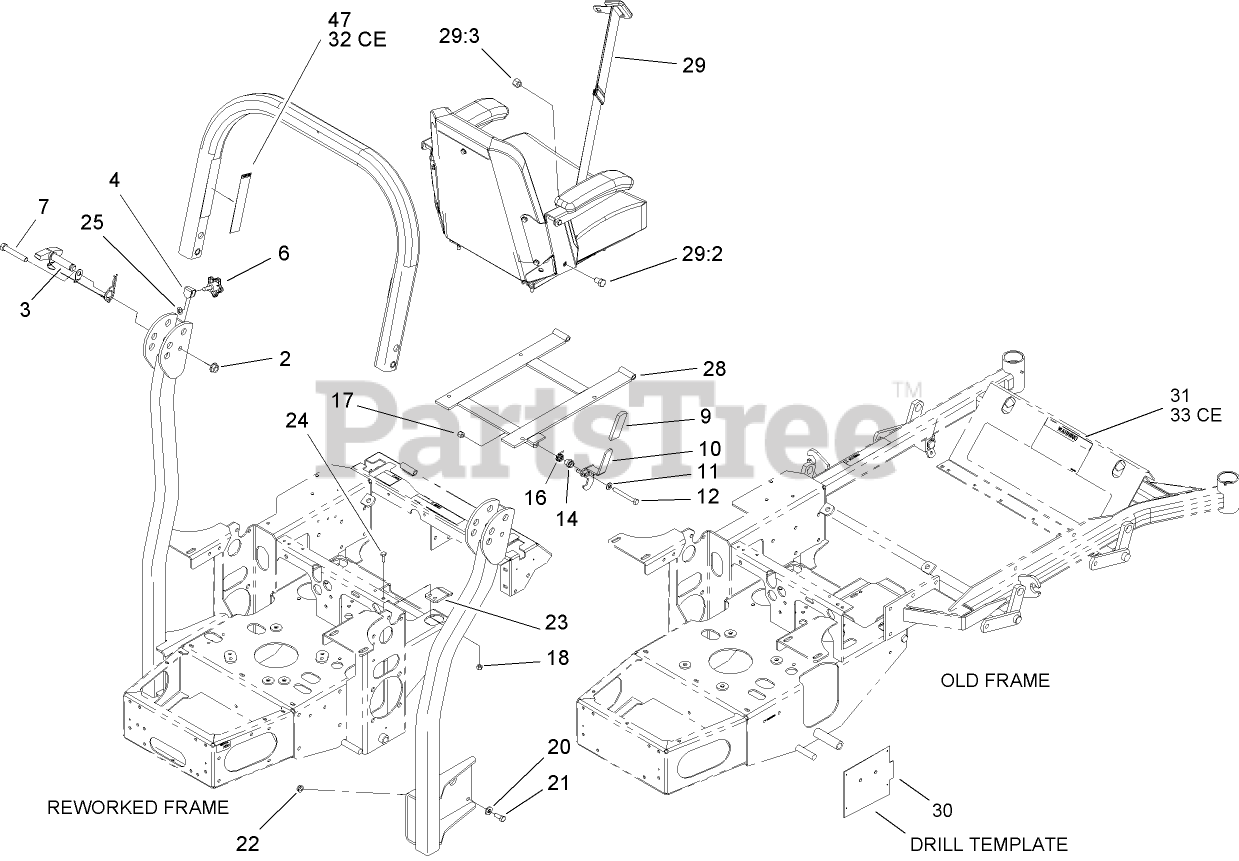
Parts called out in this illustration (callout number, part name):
2	NUT-HF
3	PIN LATCH ASM
7	SCREW-HH
9	GRIP-HANDLE
10	LATCH ASM
11	WASHER-FLAT
12	SCREW-HH
14	BUSHING-LATCH, SEAT
16	SPRING-TORSION
17	NUT-LOCK, NI
18	NUT-LOCK, NI
20	WASHER-BELLEVILLE
21	SCREW-HH
22	NUT-HHF, WHIZ
23	CATCH-LATCH, SEAT
24	SCREW-HH
25	NUT-PUSH
28	SEAT SUPPORT FRAME ASM
29	SEATBELT KIT
29:2	SCREW-HH
29:3	NUT-LOCK, NI
30	TEMPLATE-MOUNT, ROPS
31	DECAL-WARNING
32	DECAL-WARNING
33	DECAL-DANGER, SLOPE
47	DECAL-WARNING, FOLDING ROPS
